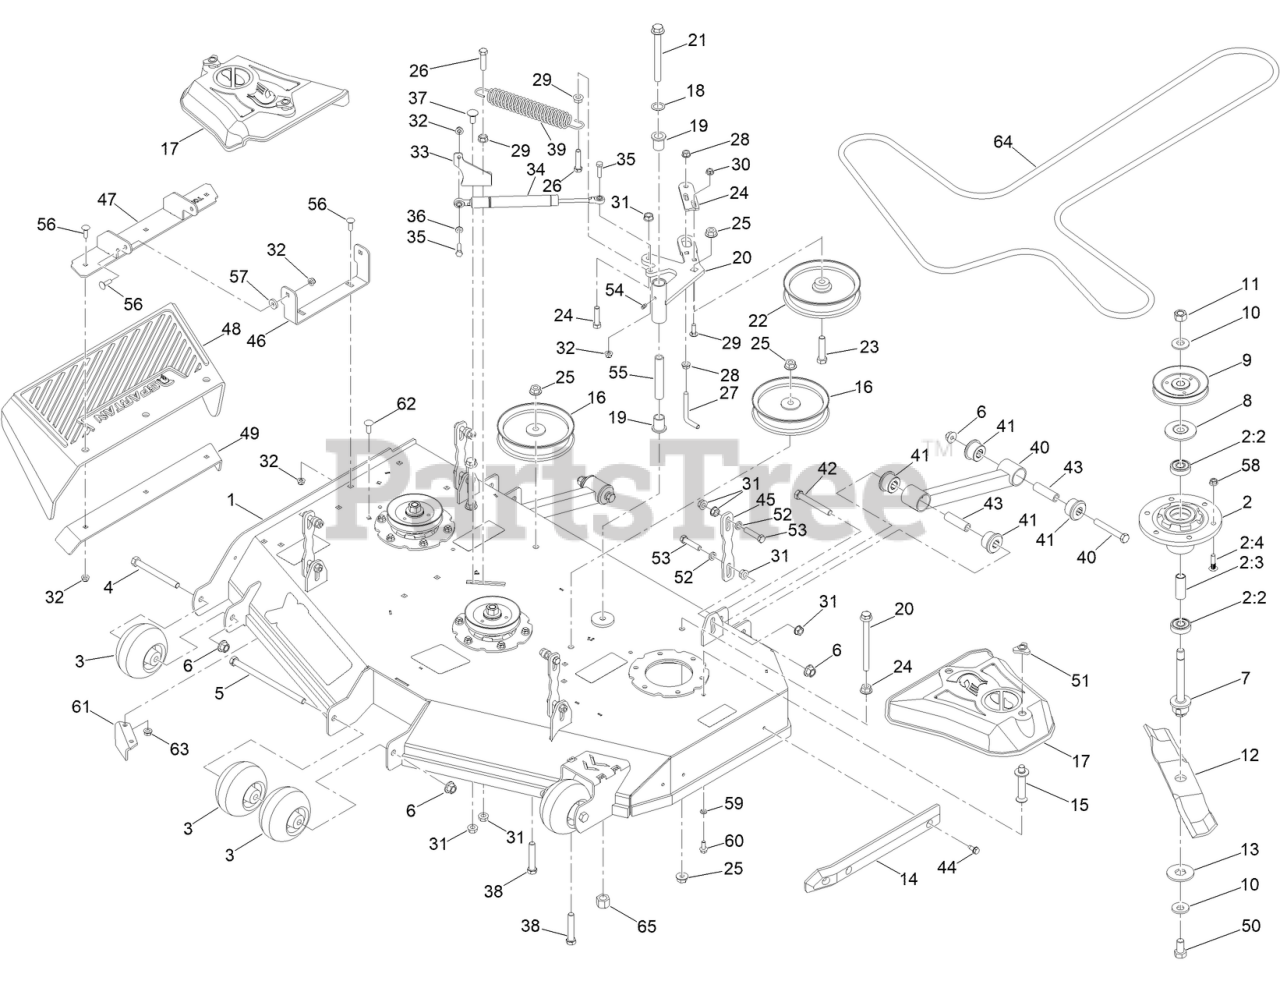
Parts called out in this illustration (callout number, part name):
1	ASM- 48" DECK W/DECALS
2	SPINDLE ASM 5IN DECK
2:2	BEARING
2:3	SPACER, BEARING
2:4	BOLT-ROUND HEAD
3	MWR ANTI-SCALP WHL W/O GREASE FITTING
4	SCREW-HH
5	1/2-13 X 8-1/2 HEX C/S GR 2 ZINC YELLOW
6	NUT-LOCK
7	SHAFT - SPINDLE
8	GUARD-BEARING TOP 0.673IN
9	PULLEY
10	M16 SPRING WASHER (39MMOD/ 3.9MM THK)
11	M16X1.5 C8.8 HEX NUT
12	BLADE-ROTARY
13	WASHER-HEX
14	MWR NYLON DECK GUARD
15	PIN-BELT COVER
16	6-3/4IN IDLER PULLEY 15/16IN SPACER ASSY
17	COVER BELT
18	.767IDX1.125ODX.016 THK TRIP WV WASHER
19	3/4IN ID X15/16IN OD X 1-1/8IN FLNG BUSH
20	MWR DECK IDLER PULLEY ARM ASSY PAINT
21	1/2-13 X 5-1/2 HEX FLANGE BOLT GR 8 ZY
22	6-3/4IN IDLER PULLEY 7/16IN SPACER ASM
23	SCREW-HH
24	DECK IDLER PULLEY BELT RETNR BRKT PAINT
25	NUT-HHF
26	SCREW-HH
27	BOLT-L
28	3/8-16 HEX FLANGE NUT W/SERR ZINC YELLOW
29	BOLT-CARR
31	NUT-HF
32	NUT-HF, NI
33	BRACKET- IDLER DAMPER
34	IDLER GAS SPRING
35	SCREW-HH
36	.312IDX.625ODX.062 THK THRUST BRG OI BRZ
37	SCREW-CARR
38	1/2-13 X 2-3/4 HEX FLANGE BOLT (GR.8) YZ
39	MWR DECK SPRING
40	RZ MWR DECK STABLZR ASSY
41	RED A80 SUSP BUSHING
42	1/2-13 X 3-3/4 HEX C/S (GR.5) ZC/YEL
43	UTV A-ARM BUSHING SLEEVE
44	SCREW-HWH, THREAD CUT
45	RZ MWR DECK ACTUATOR CONN LINK PAINT
46	BRACKET-CHUTE
47	DECK CHUTE HINGE ASM
48	RZ MWR RUBBER DISCHARGE CHUTE
49	MWR DECK CHUTE HINGE BACKER BRKT
50	M16X1.5-30MM C10.9 HEX BOLT
51	NUT-KNOB
52	.443 ID X .749 OD X .125 THK NYLON BLACK
53	SCREW-HH
54	1/4IN DRIVE TYPE GREASE FITTING YZ
55	MWR INNER IDLER SPACER
56	5/16-18 X 1 CARRIAGE BOLT GR 8 YZ
57	.312 ID X .875OD X .1875 THK F/W NYL
59	WASHER-LOCK
60	SCREW-HHF
61	BAFFLE-DISCHARGE
62	SCREW-CARR
63	NUT-HF, NI
64	BELT-V
65	NUT-LOCK, NI
